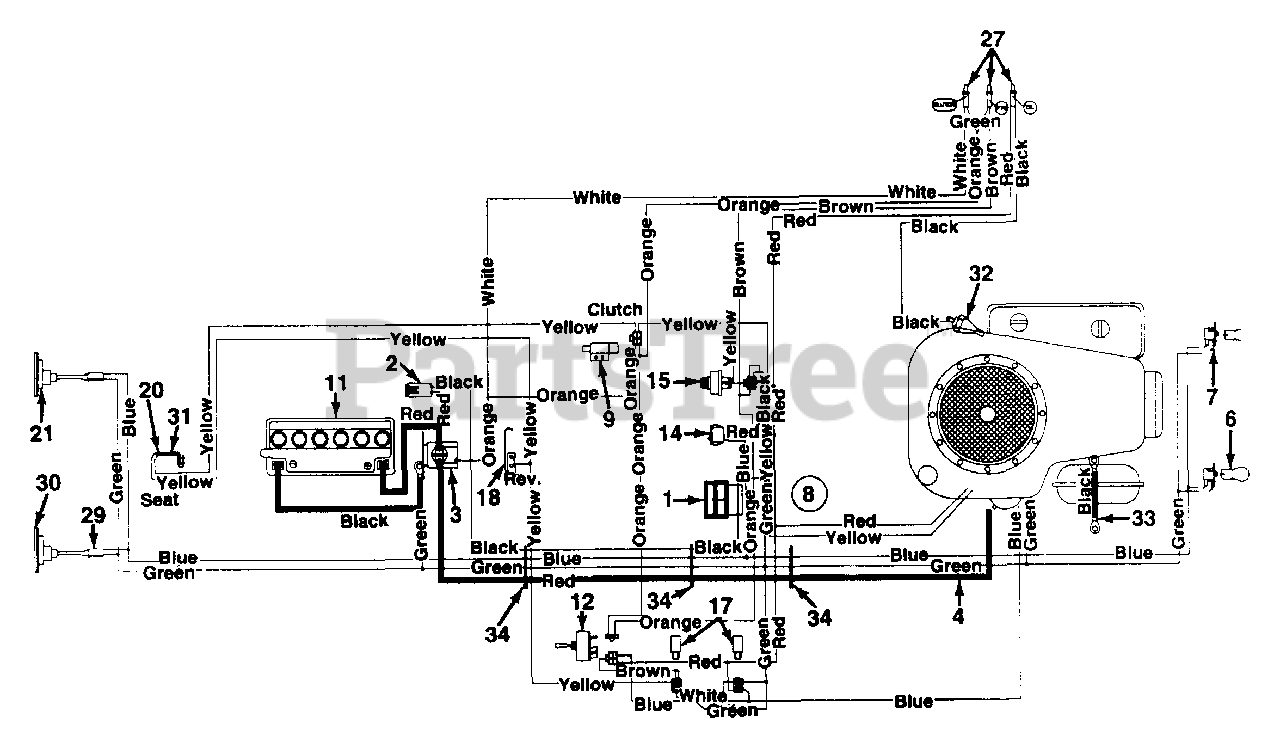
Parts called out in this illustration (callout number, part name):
1	Ammeter
2	Fuse 20 Amps
3	Solenoid
4	Wire 30" Lg.
6	Bulb
7	Socket
8	Wire Harness
9	Safety Switch (Clutch)
11	Battery 12V
12	Switch (PTO)
14	Light Switch
15	Ignition Switch
17	Relay
18	Spring Lever
20	Safety Switch (Seat)
21	Taillight
27	Bulb
29	Taillight Harness
30	Bulb
31	Safety Switch (Seat)
32	Oil Pressure Switch
33	Wire 7.5" Lg.
